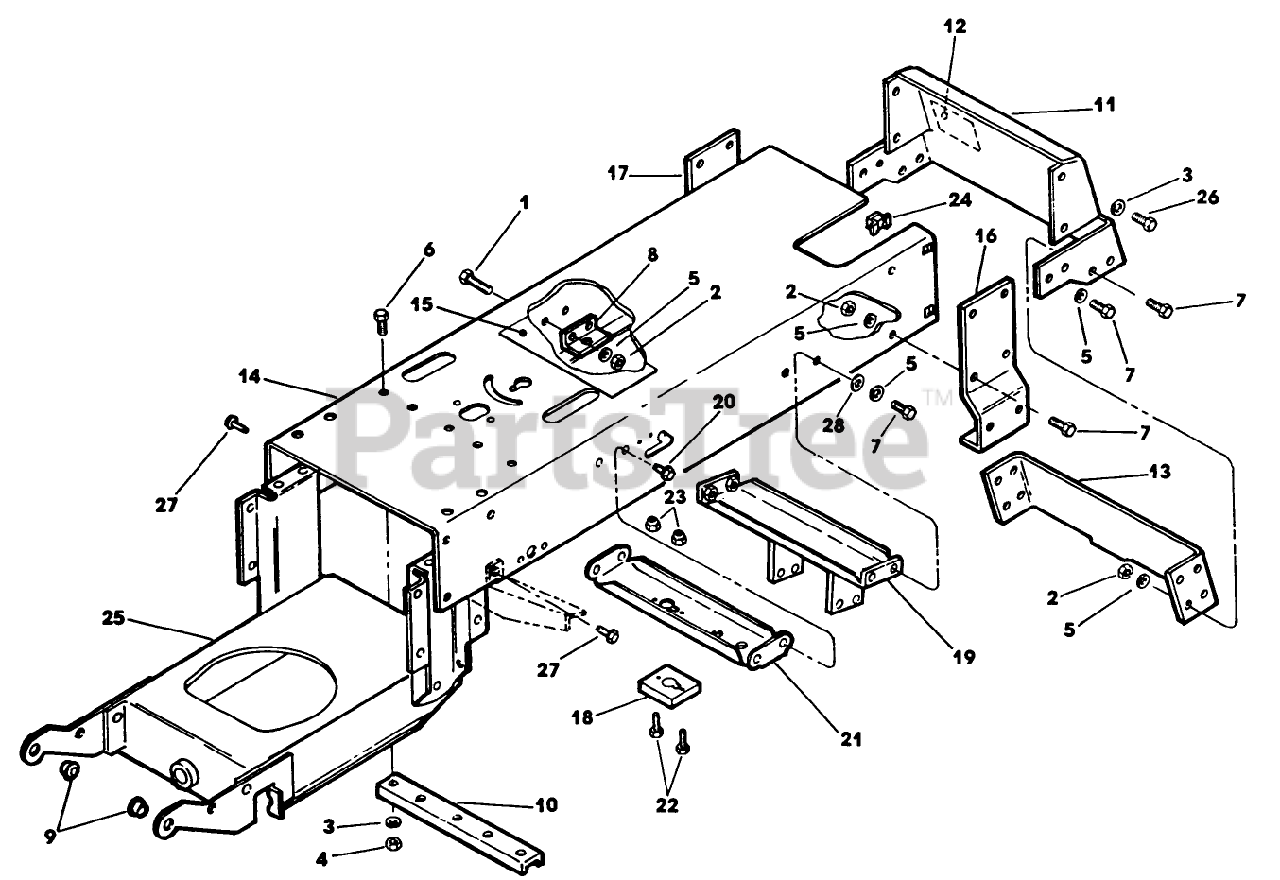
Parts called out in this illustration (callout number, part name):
2	NUT
4	NUT SS
5	WASHER
9	BEARING-NYLINER
18	BRACKET-SUPPORT *B
21	SUPPORT *B
22	SCREW
23	NUT-LOCK, CONE
24	NUT-SQ, CAGED
28	WASHER
